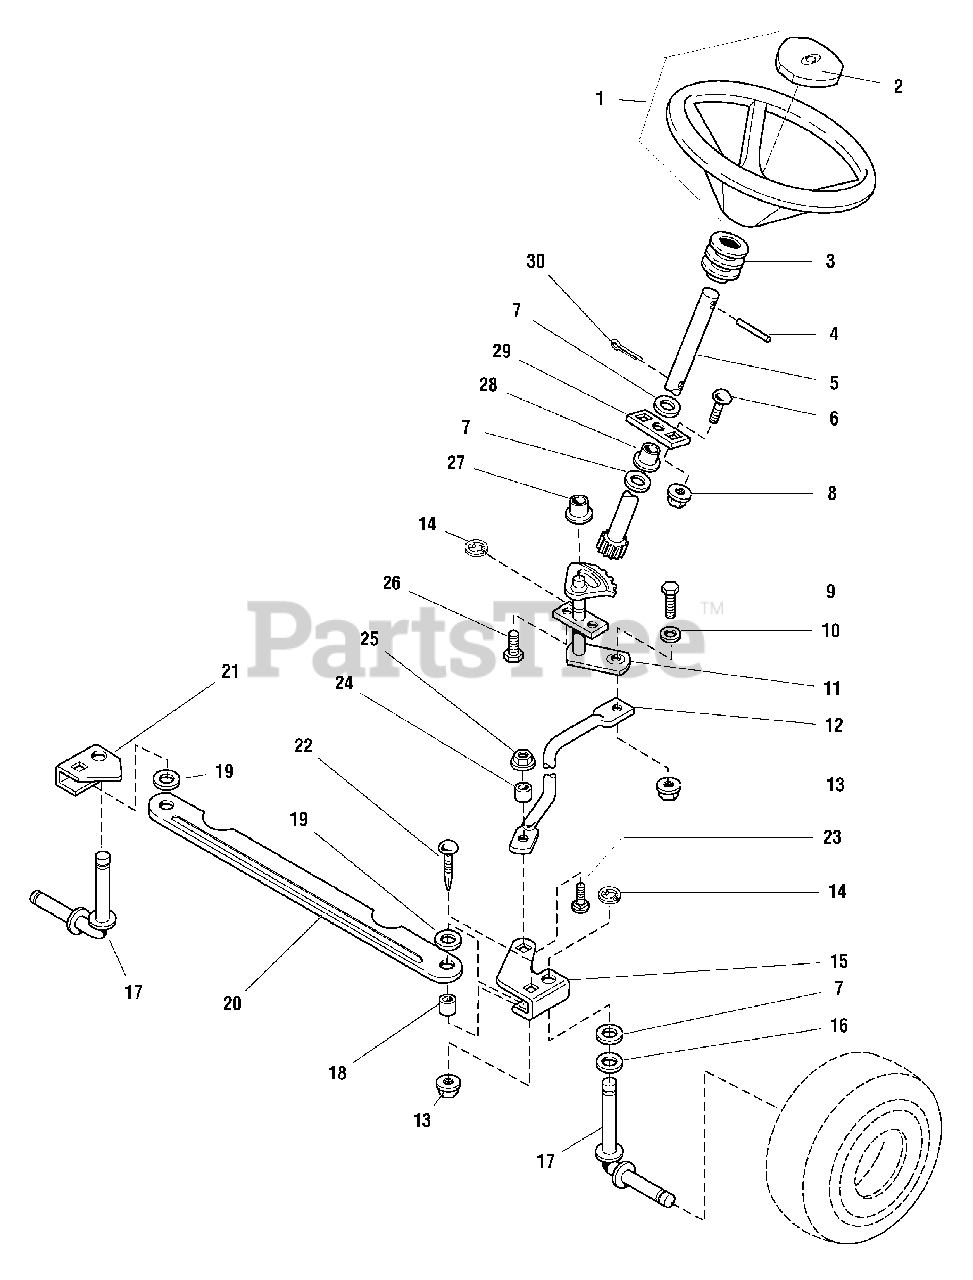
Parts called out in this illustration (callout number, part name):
1	STEERING WHEEL ASSY.,
2	CAP, Steering Wheel
4	PIN, Spring, 5/16 x 2-1/2
5	SHAFT ASSY., Steering
6	CARRIAGE BOLT, 3/8-16 x 1
7	WASHER
8	NUT, Flange Lock ,Whiz, 3/8-16
9	CAPSCREW, 3/8-16 x 1-3/8
11	STEERING GEAR ASSY.
13	NUT, Hex, Flange Lock. 3/8-16
15	ARM, Steering, LH
17	SPINDLE ASSY.
19	WASHER, 5/8
21	ARM, Steering, RH
22	CARRIAGE BOLT, 3/8-16 x 1-1/4
23	CARRIAGE BOLT, 5/16-18 x 1
25	NUT, Hex, Flange Lock, 5/16-18
26	SCREW, Taptite, 5/16-18 x 3/4
29	PLATE, Steering, Mounting
30	PIN, Cotter, 3/16 x 1-1/4
